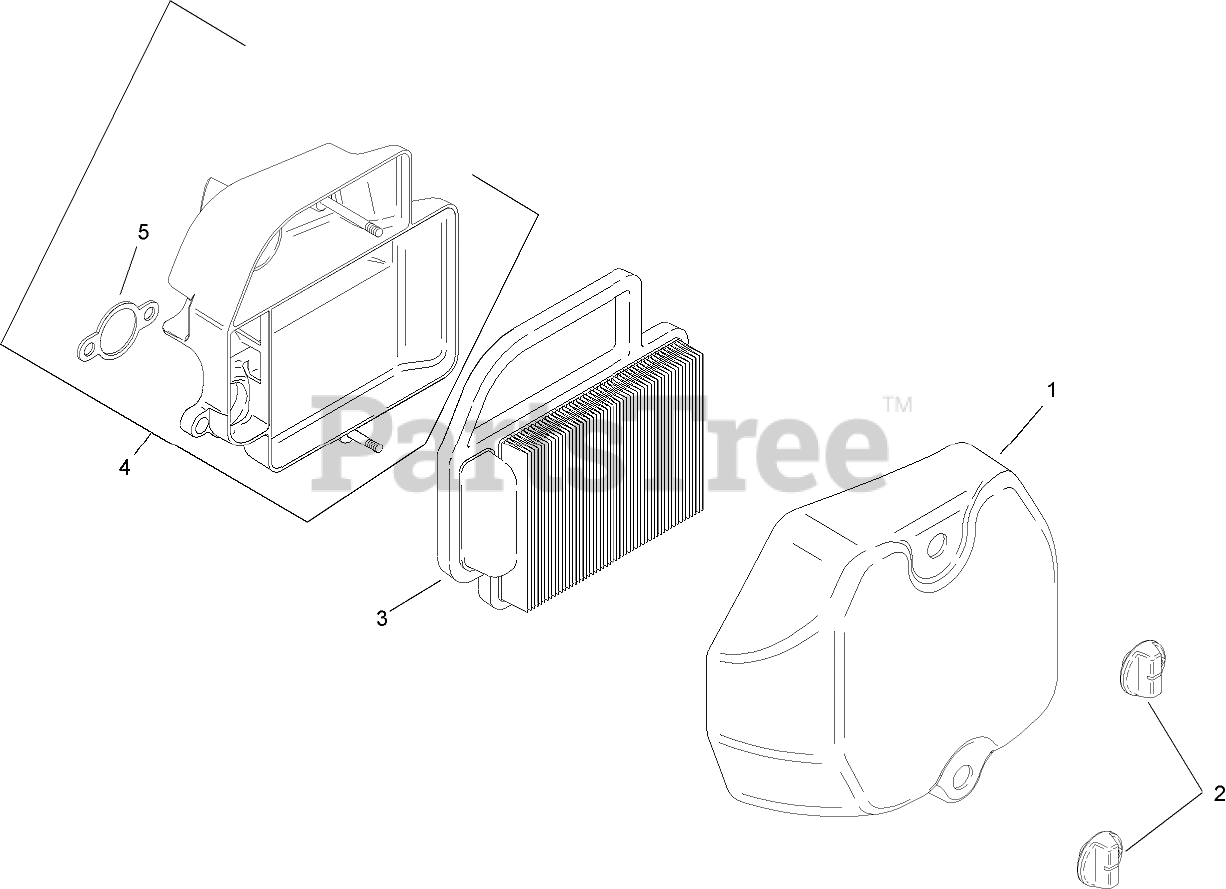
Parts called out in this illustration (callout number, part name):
1	AIR CLEANER COVER ASM
2	KNOB-COVER
3	Element-Air Cleaner
4	Air Cleaner Base Kit (Includes 5)
5	Gasket-Base, Air Cleaner
